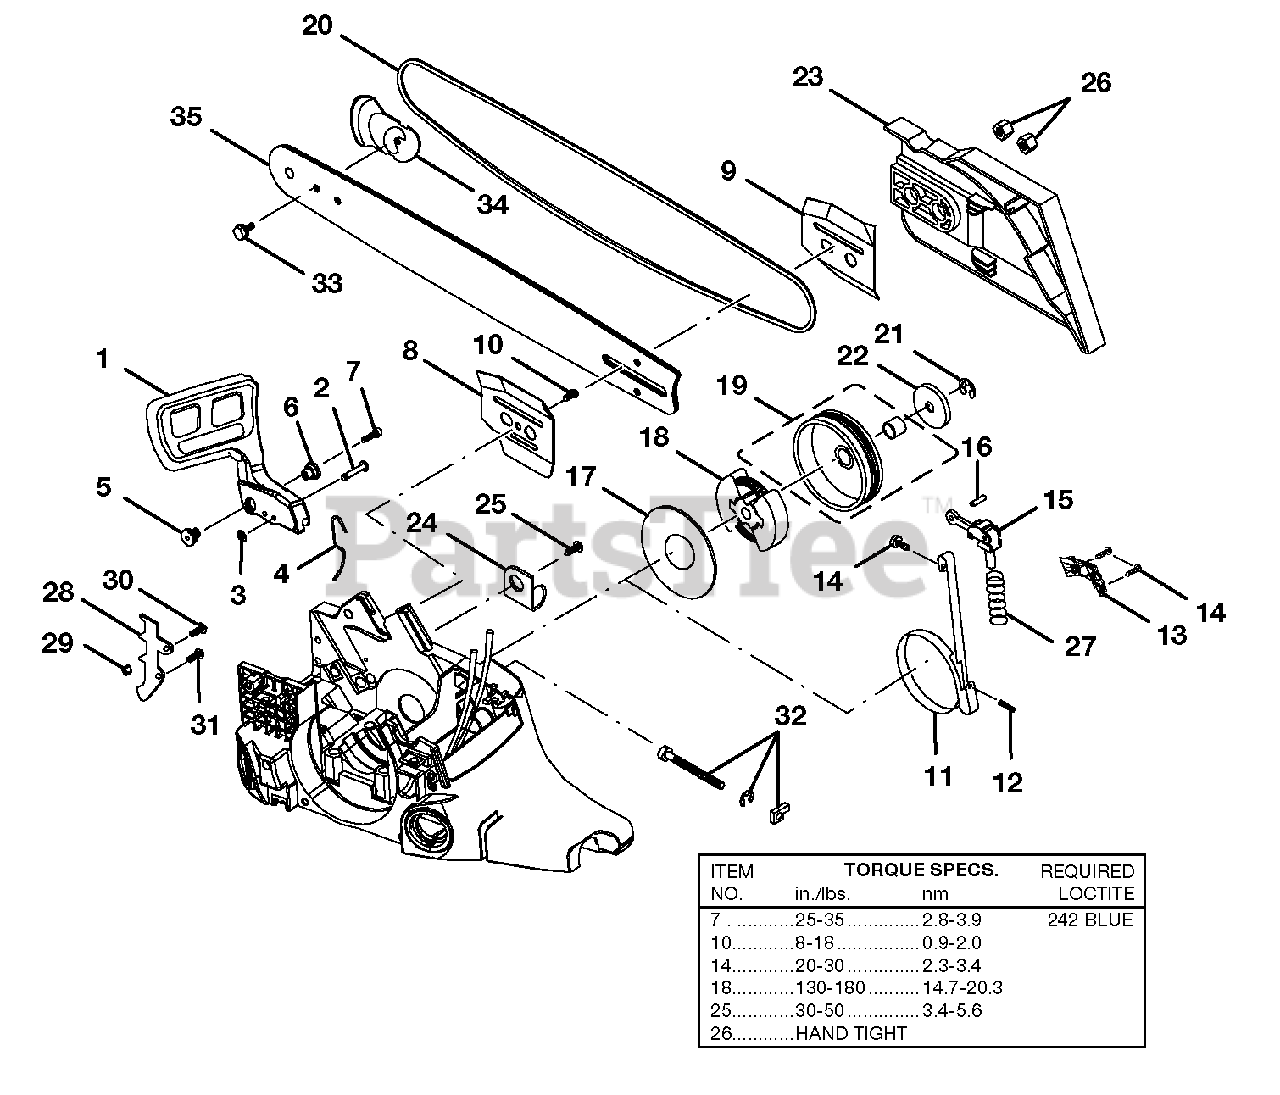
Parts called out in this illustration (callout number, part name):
1	HAND GUARD
2	HAND GUARD ACTUATING PIN
3	RETAINING RING
4	SPRING, HANDGUARD
5	PIVOT, LH
6	PIVOT, RH
7	SCREW (8-32 x 5/8 in.)
8	PLATE, GUIDE BAR
9	PLATE, GUIDE BAR
10	SCREW (6-19 x 1/2 in.)
11	BRAKE BAND
12	PIN, ROLL
13	BRAKE BAND COVER
14	SCREW (8-16 x .320 )
15	CHAIN BRAKE LINK
16	PIN, ROLL
17	THRUST WASHER
18	CLUTCH & HARDWARE
19	SPROKET DRUM & BEARING ASSEMBLY (.325 PITCH)
20	CHAIN
21	RING, RETAINING
23	DRIVE CASE COVER
24	CHAIN CATCHER
25	SCREW (10-24 x 1/2 in.)
27	SPRING, COMPRESSION
28	BUMPER SPIKE
29	LOCK NUT, HEX (10-24)
31	SCREW, TRUSS HD.
32	ADJUSTING PIN KIT
33	SCREW - SAFETY TIP (HEX HD.)
34	SAFETY TIP
35	GUIDE BAR
